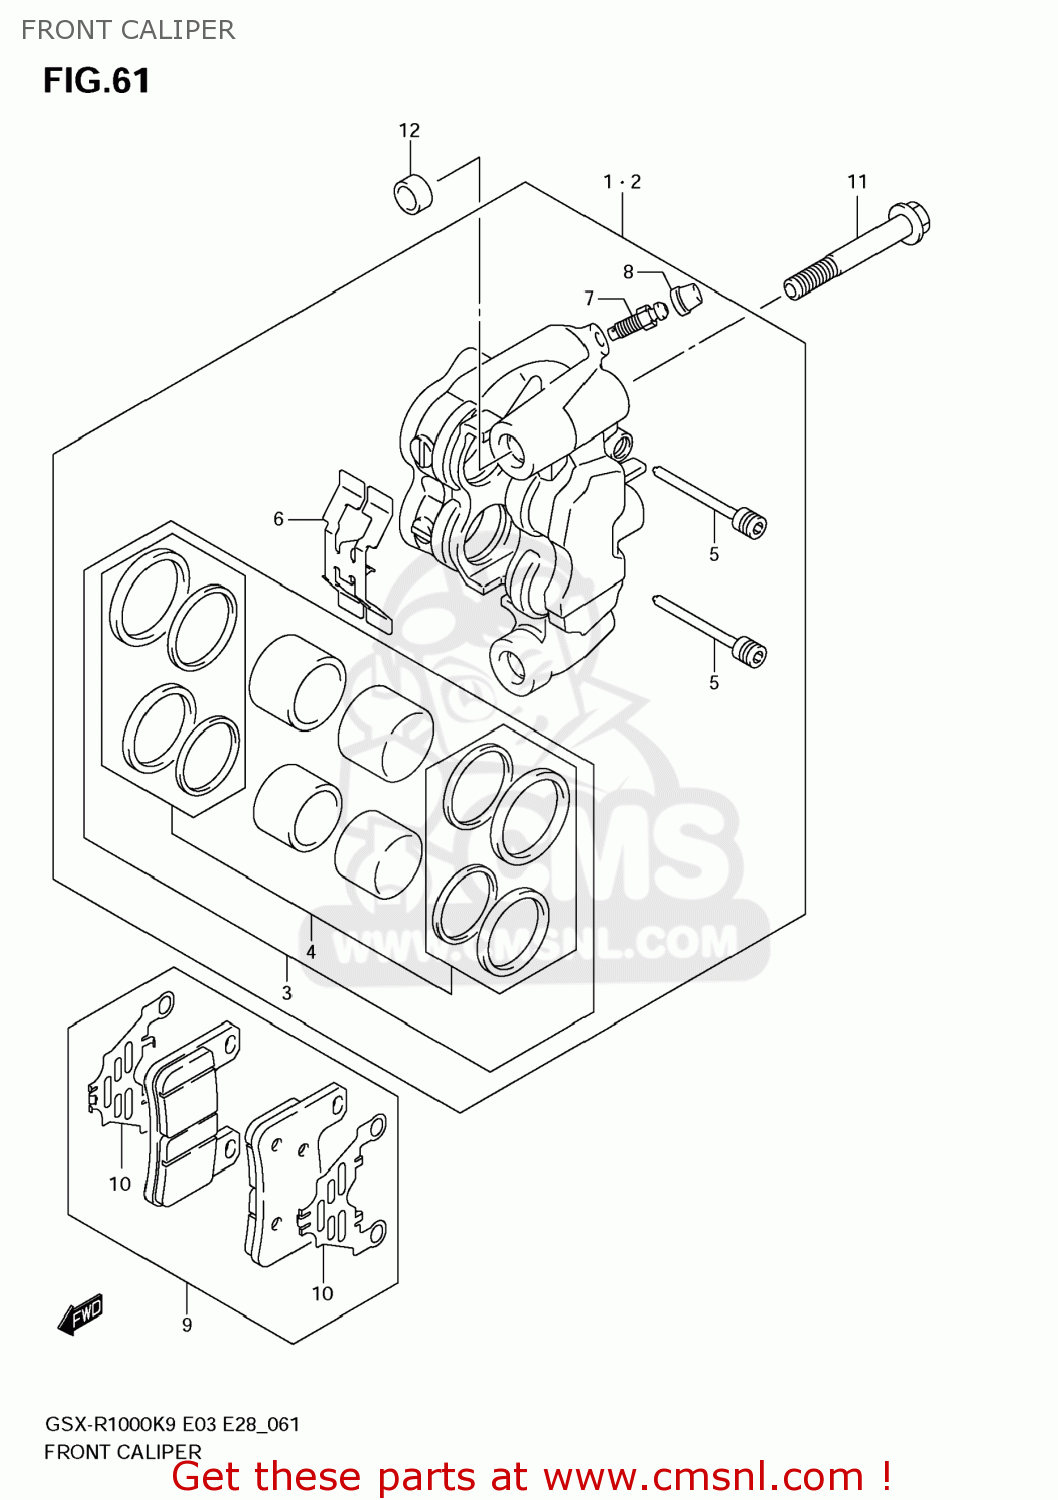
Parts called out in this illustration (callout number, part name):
1	CALIPER ASSY,FR,R
2	CALIPER ASSY,FR,L
3	PISTON SET
4	SEAL SET,PISTON
5	PIN,PAD
6	SPRING,PAD
7	BLEEDER
8	CAP,BLEEDER PLUG
9	PAD & SHIM SET (NAS)
10	SHIM
11	BOLT(10X70)
12	PIN,CALIPER
